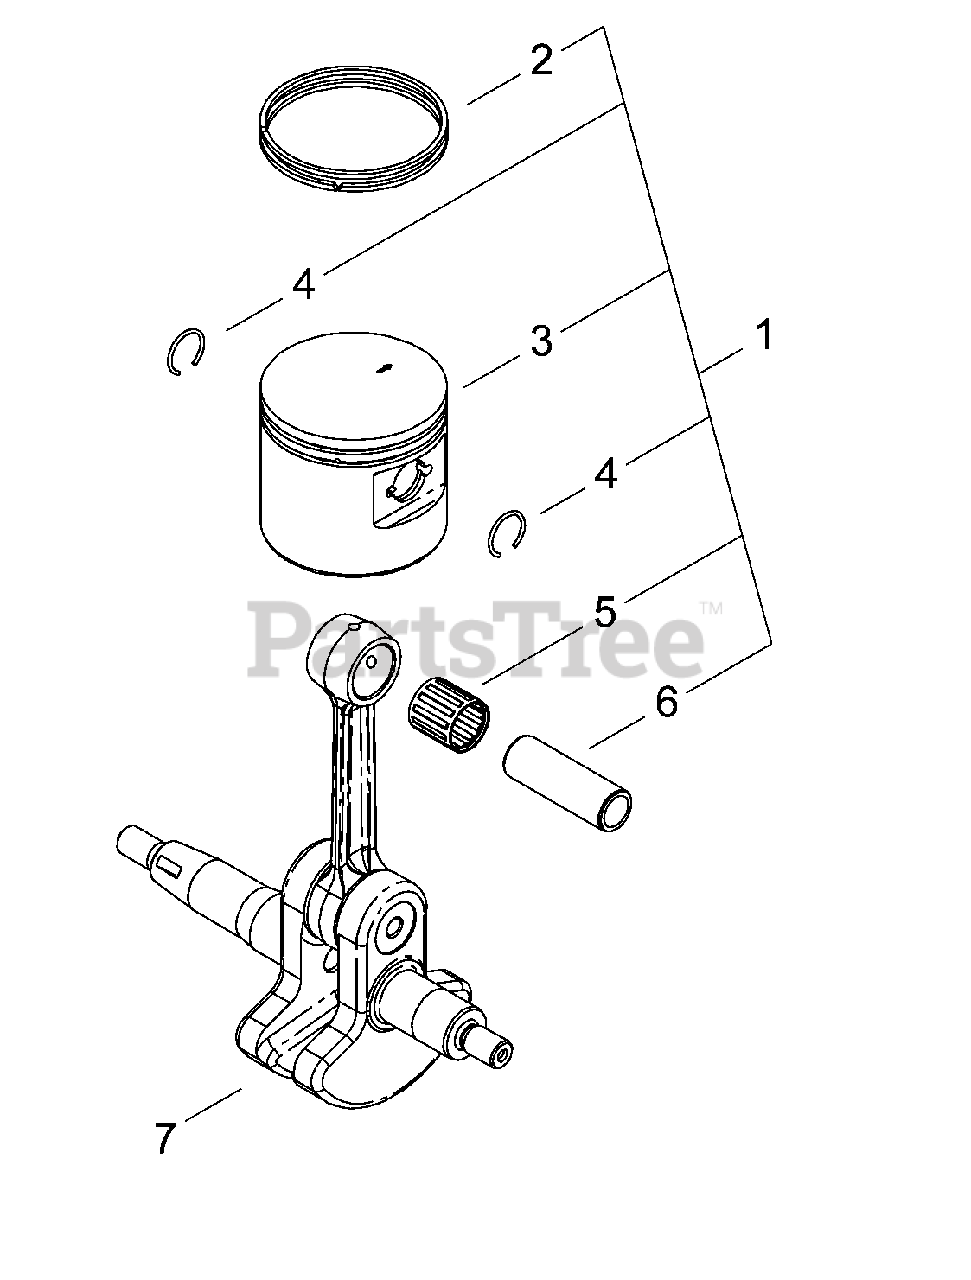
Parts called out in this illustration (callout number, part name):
1	PISTON KIT
2	RING, PISTON
3	PISTON
4	RING, RETAINING
5	BEARING, NEEDLE
6	PIN, PISTON
7	CRANKSHAFT ASSY
